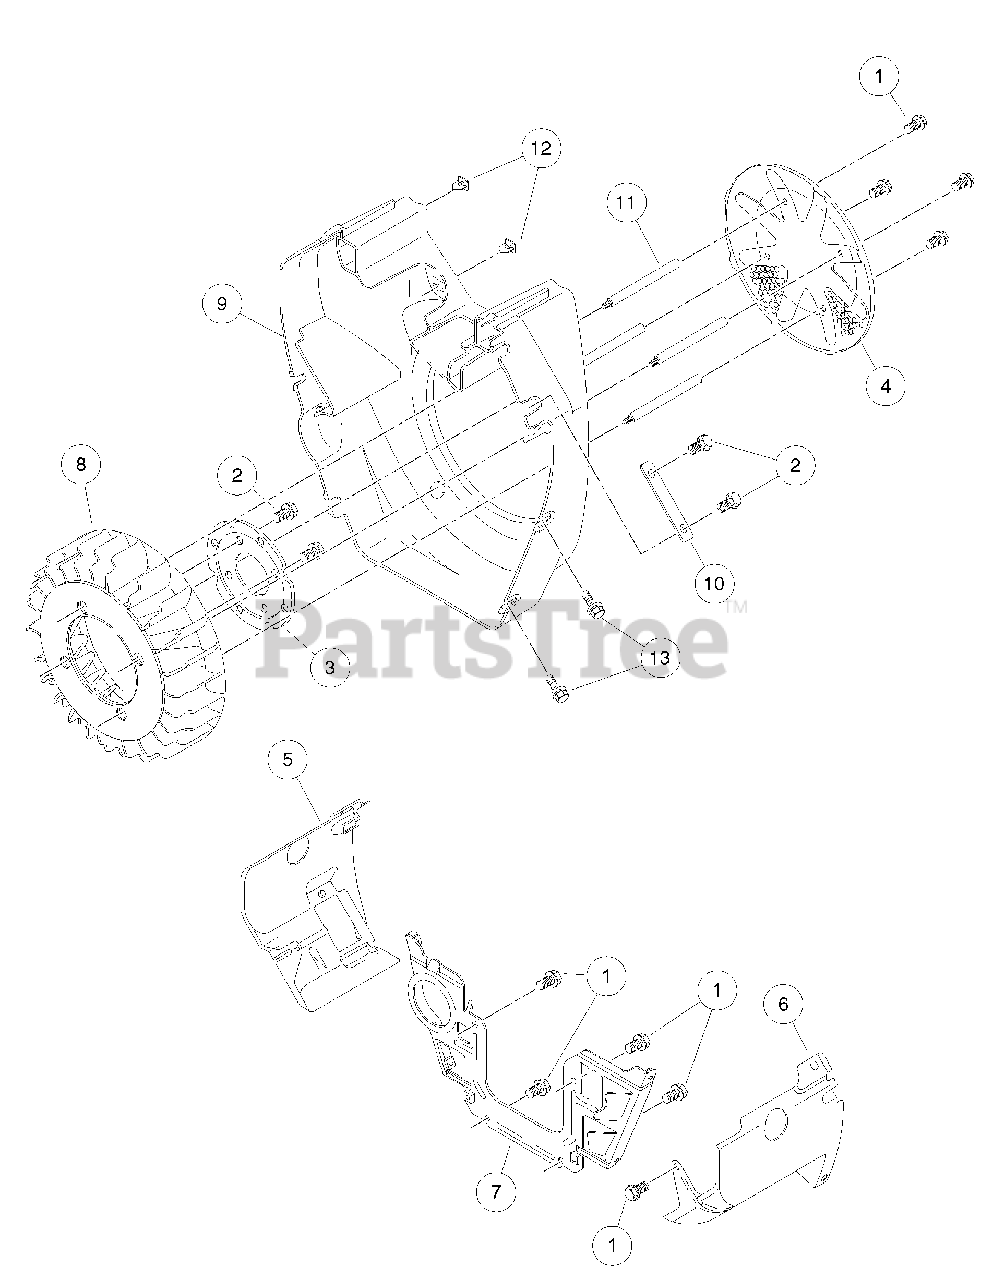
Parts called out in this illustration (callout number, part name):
1	Bolt, Flg, M6 X 1.0 X 12
2	Bolt, Flg, M6 X 1.0 X 16
3	Plate, Housing, Fan, Fh
4	Screen, Fan, Fh
5	Shroud, Engine, Rh, Fh
6	Shroud, Engine, Lh, Fh
7	Shroud, Engine, Front, Fh
8	Fan, Cooling, Fh
9	Housing, Engine, Fh
10	Washer, Housing, Fan, Fh
11	Stud, Fan Screen, Fh
12	Nut, Press In, Front Cover, Fh
13	Bolt, Oil Pickup, Fh
